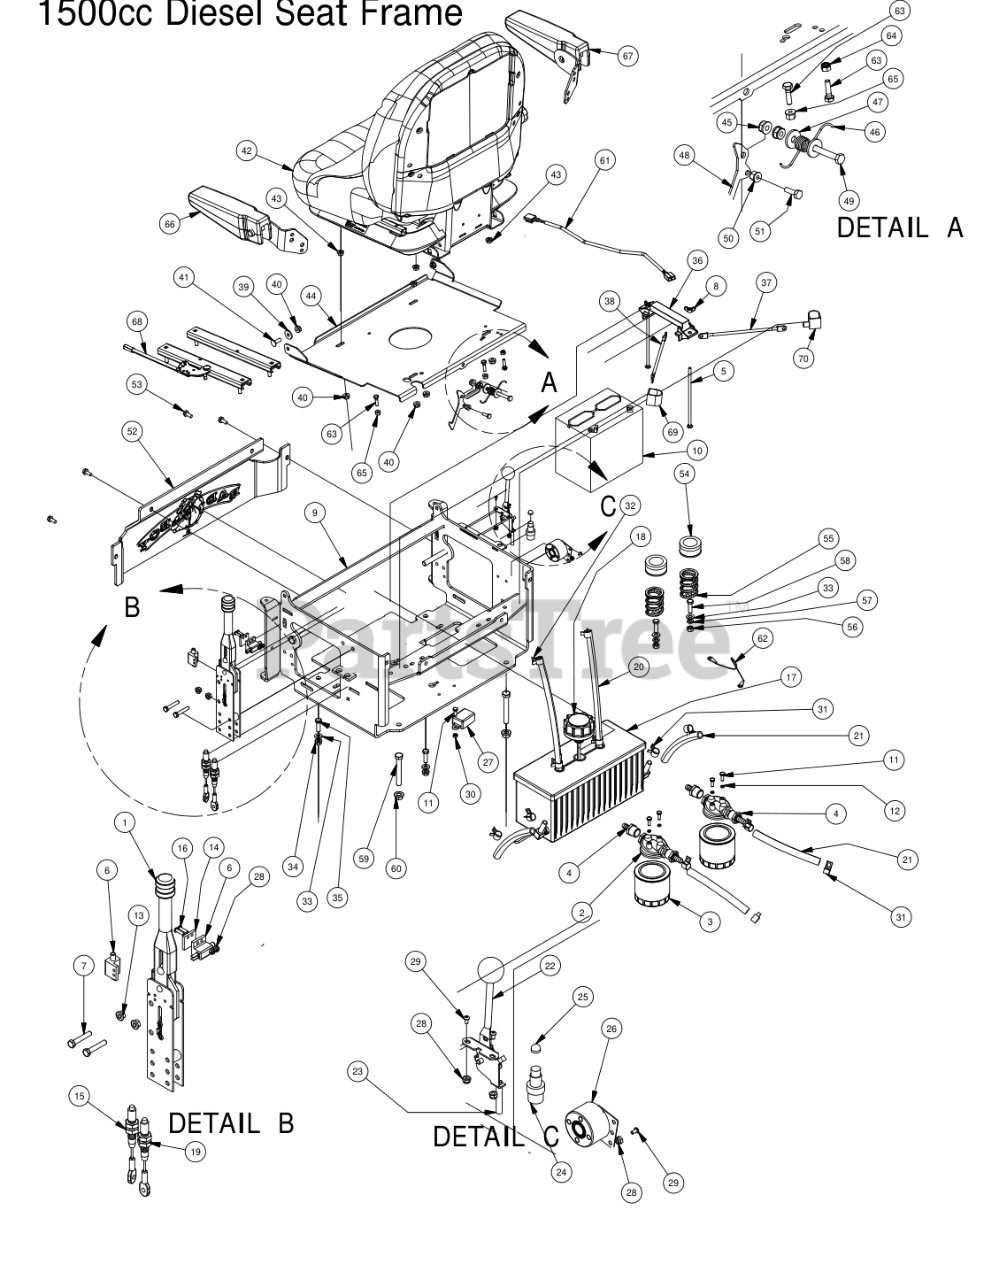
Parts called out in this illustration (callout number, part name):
1	Hand Brake Assembly
2	Filter Head
3	Hydraulic filter
4	Filter Head Fitting
5	1/4-20 X 9 Carriage Bolt
7	5/16" x 1 3/4" Hex Bolt
8	1/4" Wing Nut
9	2007 Diesel Seat Frame
10	Battery - Diesel Models - 151
11	1/4" x 3/4" Hex Bolt
12	1/4" Lock Washer
13	5/16" Flange Nut w/Serrations
14	Switch Block Plastic
15	Short Brake Cable
16	1024 x 1" Allenhead Bolt
17	Aluminum Hydraulic Tank
18	Hydraulic Tank Cap
19	Long Brake Cable
20	3/8" x 32" Clear Hose
21	1/2" x 9 1/4" Braided Hose
22	Throttle - Diesel
23	Diesel Throttle Cable Only
24	Momentary Start Switch
25	Start Switch Boot - Diesel
26	Heat Warning Piezo Buzzer
27	Auto Shut Down for Cat Diesels
28	#10 Nylock Nut
29	1024 X 5/8" Buttonhead Bolt
30	1/4" Hex Nut
31	1/2 Hose Clamp
32	3/8 hose clamp
33	3/8" Flat Washer
34	3/8" Flange Nut
35	3/8" x 1 1/4" Hex Bolt
36	Battery Hold Down
37	Black Battery Cable - Diesel
38	Red Battery Cable - Diesel
39	.360 ID Plastic Washer
40	5/16-18 Nylon Flange Nut
41	5/16" x 1" Carriage Bolt
42	Grammer Suspension Seat w/ Seat Belt
43	5/16" Flange Nut
44	Seat Plate
45	5/16-18 Nylon Flange Nut
46	Torsion Spring for Seat latch
47	.360 ID Plastic Washer
48	Seat Latch Lever
49	5/16-18 X 2 Hex C/S (GR.5) ZC
50	1/4-20 Nylon Insert flange Nut
51	1/4-20 x 1-1/4 GR 5 Hex Bolt
52	Cooler Cover
53	5/16 x 3/4 washer head type F screw
54	Seat Spring Cap Cover
55	Seat Spring
56	3/8" Hex Nut
57	3/8" Lock Washer
58	3/8" x 1 1/2" Hex Bolt
59	1/2 x 3 1/2 Flange Bolt Grade 8
60	1/2" Flange Nut
61	Seat Switch Adapter
62	Seat Cable
63	1/4-20 x 1 GR 5 hex bolt zinc
64	1/4 Nylock Nut
65	1/4-20 Nylon Insert flange Nut
66	Left Armrest Kit for Grammer Seat
67	Right Armrest Kit for Grammer Seat
68	Rails for Grammer Seat (Pair)
70	Black Boot For Ground Cable
